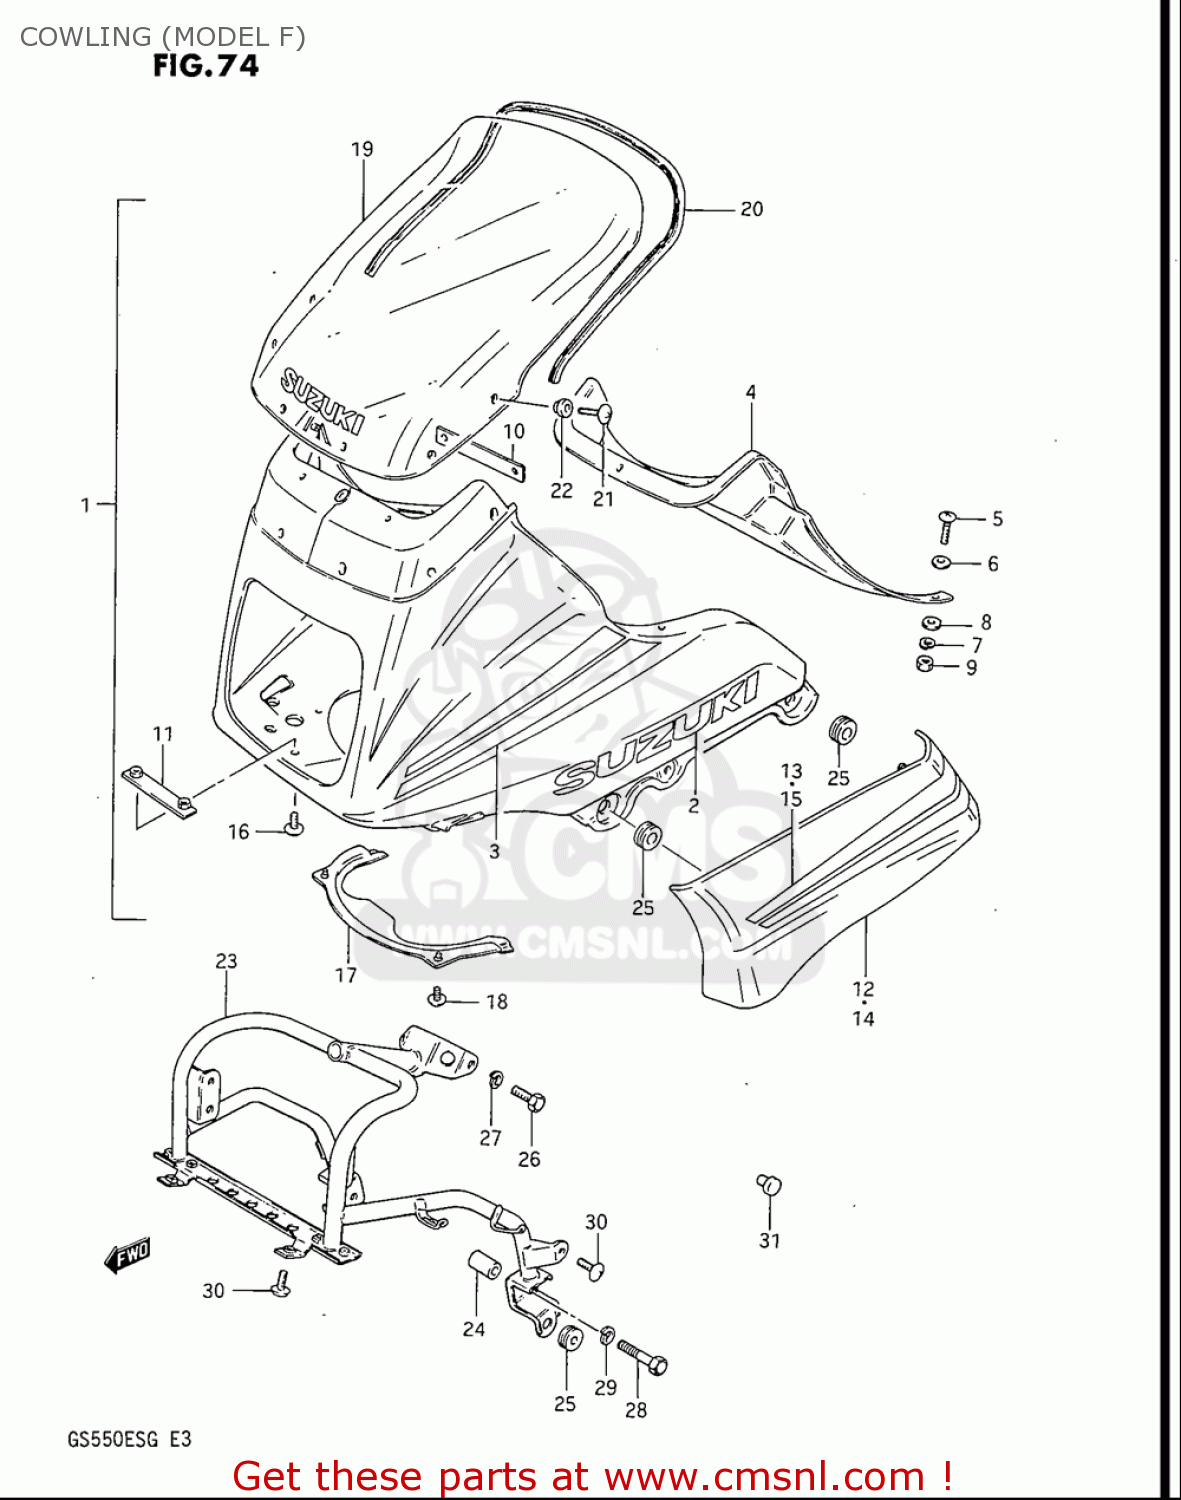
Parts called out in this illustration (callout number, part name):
2	EMBLEM
5	SCREW
6	WASHER
7	LOCK,WASHER
8	WASHER
9	NUT
12	COVER,COWLING,RIGHT
16	SCREW
18	SCREW
19	WINDOW,COWLING
20	MOLD,COWLING
21	SCREW
22	CUSHION
24	SPACER (8.2X12.5X23.5)
25	CUSHION
26	BOLT
27	WASHER,LOCK
28	BOLT
29	WASHER,LOCK
30	SCREW
31	CAP
